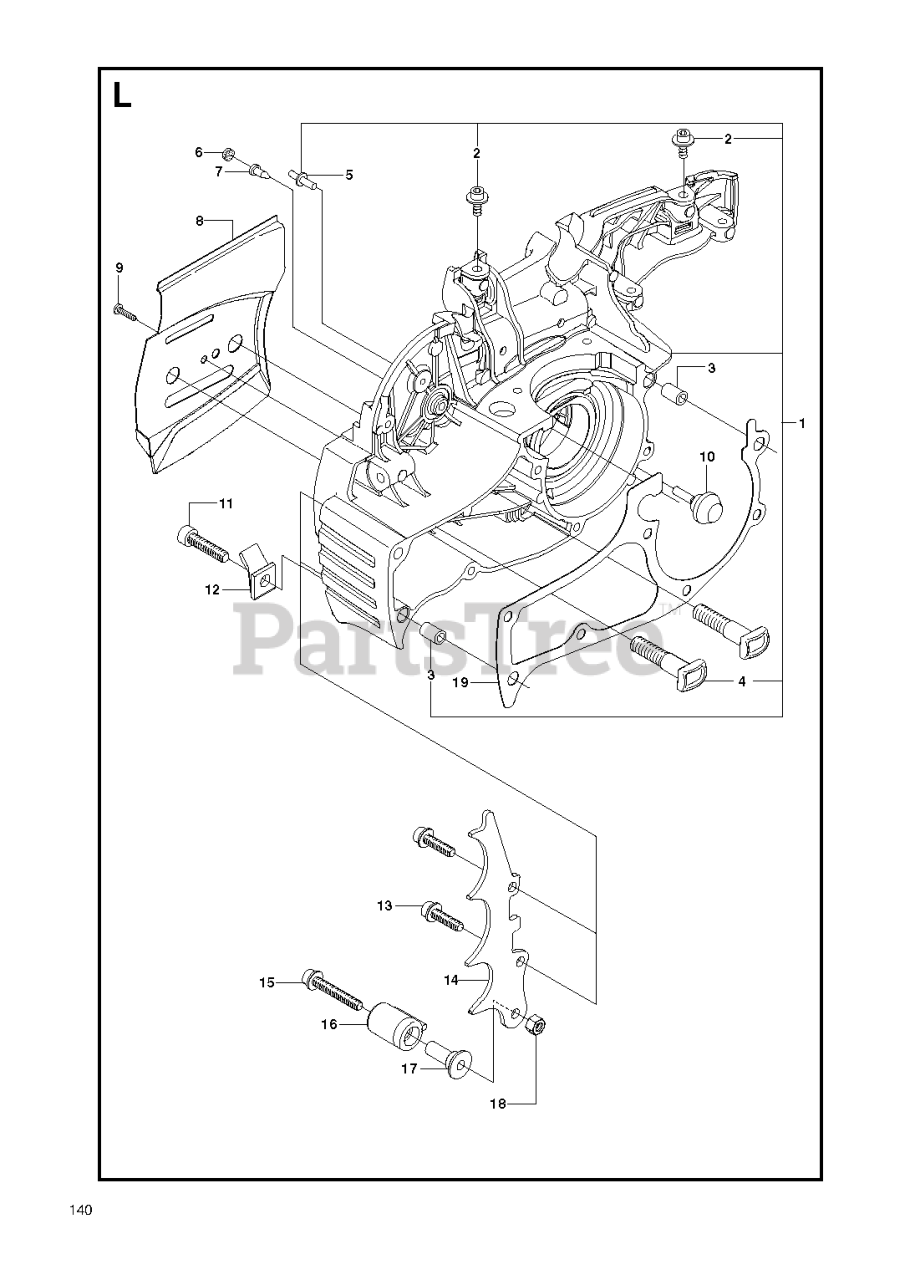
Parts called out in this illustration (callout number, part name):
1	CRANKCASE ASSY
2	RP SCREW
6	VALVE-CHECK (DUCKBILL)
7	PLUG
8	BAR PLATE
12	CHAIN CATCHER
15	SCREW
17	CHAIN CATCHER
19	GASKET SET
